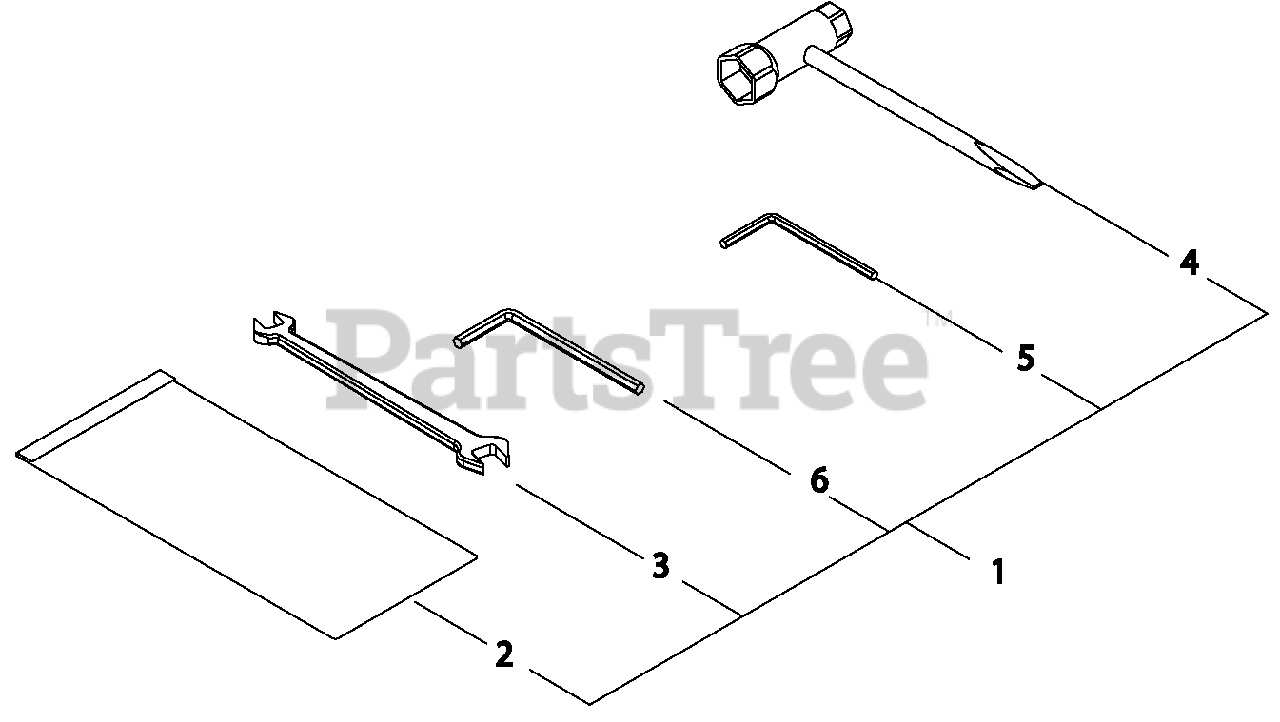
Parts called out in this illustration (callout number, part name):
1	TOOL KIT, SERVICE
2	BAG, TOOL
3	SPANNER 8×10
4	T-WRENCH 17×19 MM
5	WRENCH, ALLEN 4 MM
6	WRENCH, ALLEN 5 MM
